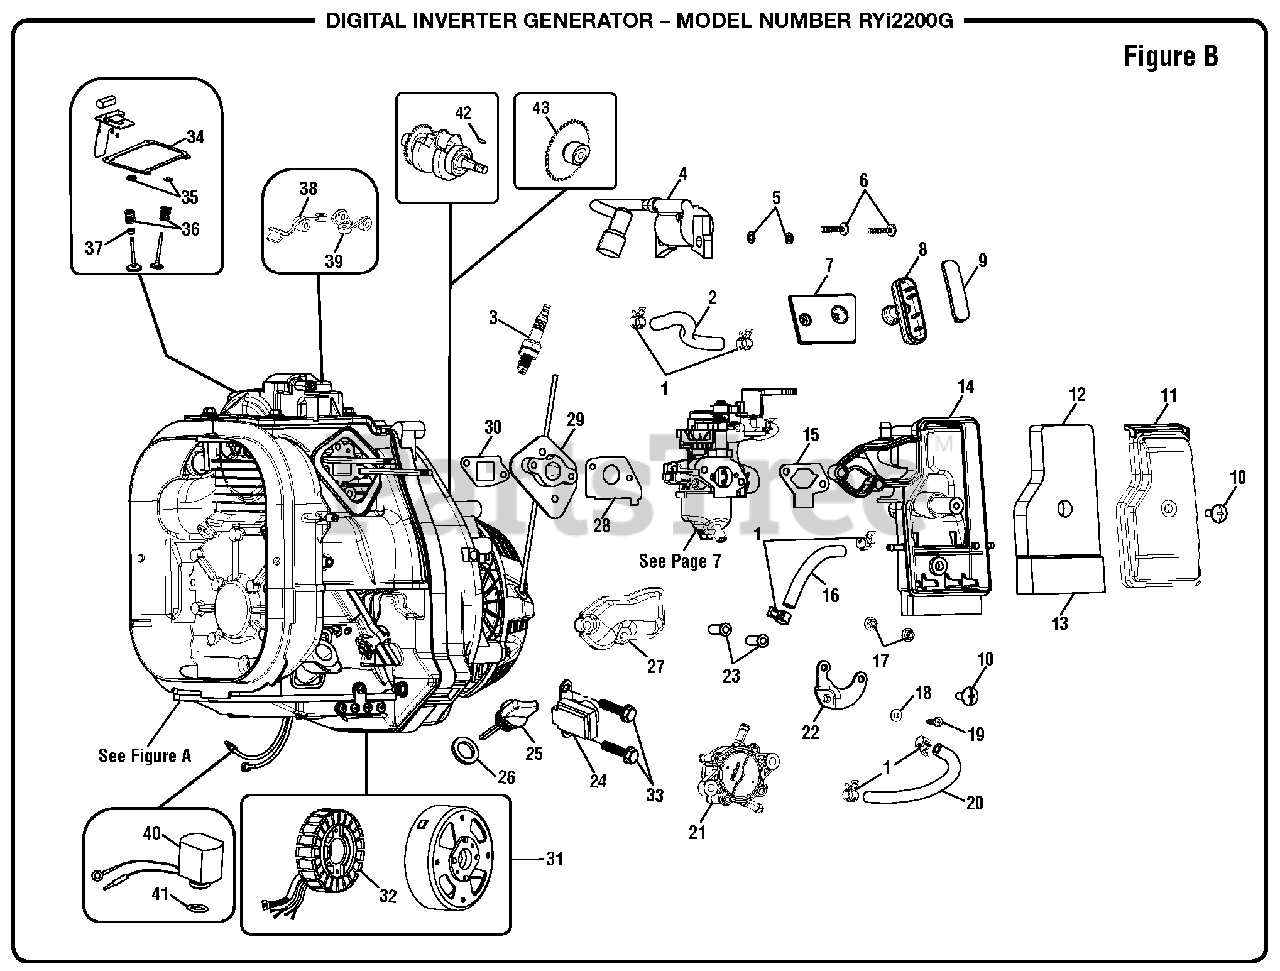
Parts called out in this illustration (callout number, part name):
1	Fuel Hose Clamp (9.5 mm)
2	Air Hose (3 Way Hose To Engine, 180 mm)
3	Spark Plug (NHSP LD7RTS)
4	Ignition Coil
5	Washer (M5)
6	Screw (M4.8 x 19 mm)
7	Start Rope Cover
8	Recoil Handle
9	Handle Cover
10	Screw (M8 x 16 mm, Truss Hd.)
11	Air Cleaner Baffle
12	Air Cleaner Filter
13	Air Cleaner Filter
14	Air Cleaner Body
15	Intake Pipe Gasket
16	Fuel Hose (Fuel Pump To Fuel Valve, 95 mm)
17	Flange Nut (M5)
18	Washer (ID4.2 x OD10 x 1t)
19	Screw (M4.2 x 12 mm, Phillips Pan Hd.)
20	Fuel Hose(Engine To Fuel Pump, 140 mm)
21	Fuel Pump
22	Fuel Pump Bracket
23	Air Cleaner Body Nesting
24	Pick-up Coil
25	Engine Oil Dipstick
26	Oil Dipstick Seal
27	Intake Pipe Top Hood
28	Carburetor Gasket
29	Intake Seat
30	Insulating Board Gasket
31	Alternator Assembly
32	Stator Assembly
33	Screw (M6 x 100 mm)
34	Head Gasket
35	Valve Retainer
36	Valve spring
38	Intake Rocker Assembly
39	Exhaust Rocker Assembly
40	Oil Sensor
41	Oil Sensor Seal
42	Engine Shaft Key
43	Engine Cam
